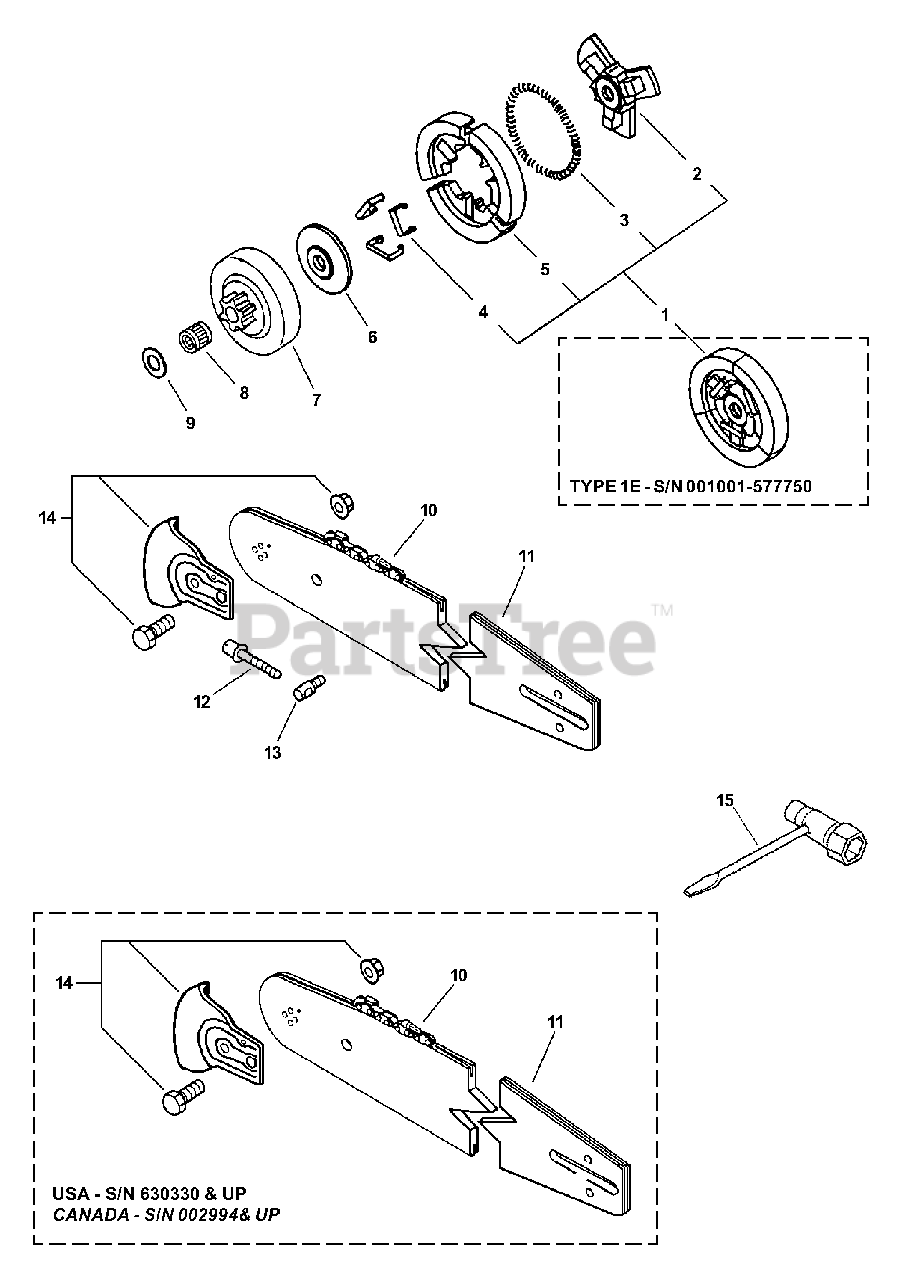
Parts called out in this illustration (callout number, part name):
1	CLUTCH ASSY
2	HUB, CLUTCH
3	SPRING, CLUTCH
4	CLIP, SPRING
5	SHOE, CLUTCH
5	CLUTCH SHOE SET
6	PLATE, CLUTCH
7	DRUM, CLUTCH
8	BEARING, NEEDLE
9	WASHER
10	SAW CHAIN - 12" (30cm)
10	SAW CHAIN - 14" (35cm)
10	SAW CHAIN - 16" (40cm)
11	GUIDE BAR - 12" (30cm)
11	GUIDE BAR - 14" (35cm)
11	GUIDE BAR - 16" (40cm)
11	GUIDE BAR - 12" (30cm) Intenz
11	GUIDE BAR - 14" (35cm) Intenz
11	GUIDE BAR - 16" (40cm) Intenz
12	SCREW, TENSIONER
13	TENSIONER, CHAIN
14	KICK GUARD KIT
15	T-WRENCH - 10X19mm
